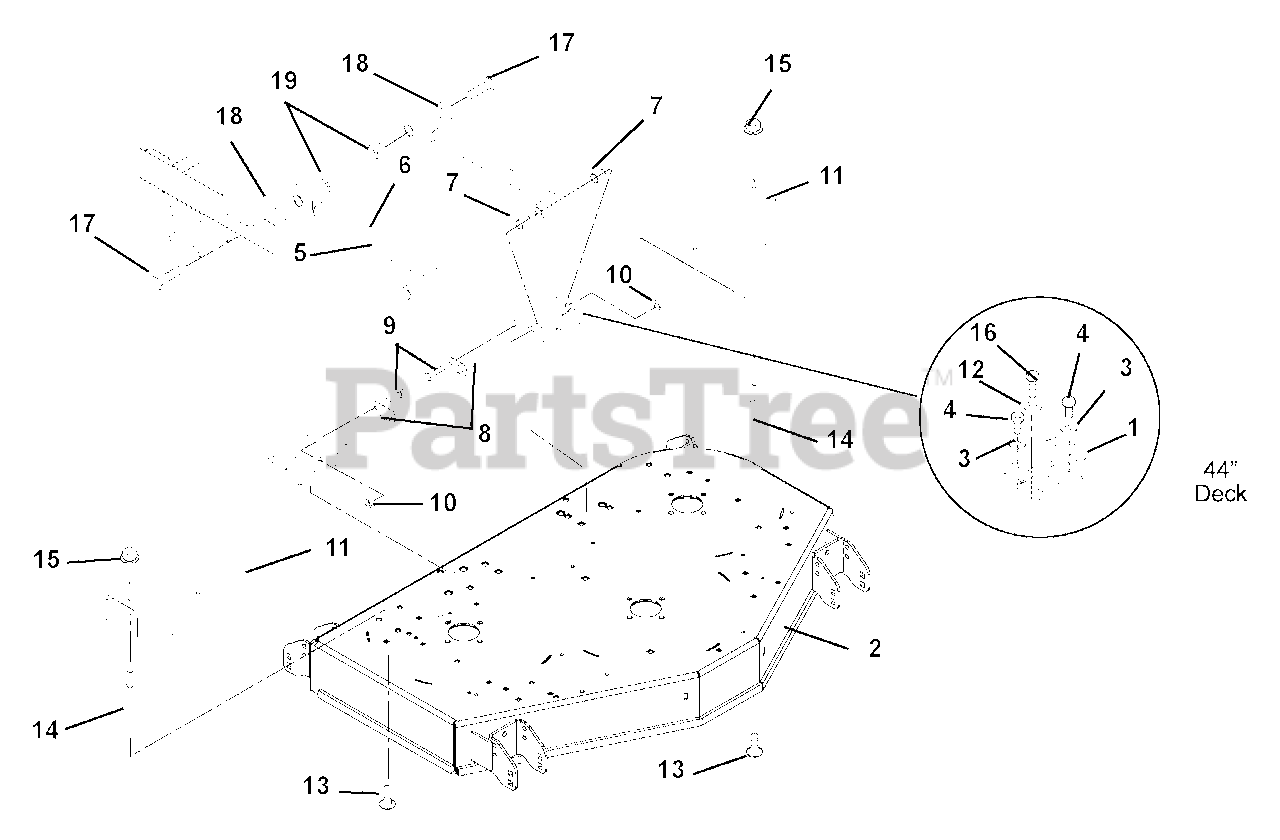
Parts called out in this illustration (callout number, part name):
1	BRACKET, MOWER MOUNT (REAR)
2	WMT, 44 REAR DISCHARGE
3	@WSHR-LK .50X.125 REG YWZC
4	@BLT-HEX .50-13X1.00 GR5 YWZC
5	ASSY, MOWER MOUNTING
6	MOWER MTG ARM - BLACK
7	BRG, .750 X .875 X 1.000
8	WELDMENT, MOWER MTG. PIN
9	@BLT-HEX .38-16X.75 GR5 YWZC
10	@NUT-LK-TOP-FLG .38-16 YWZC
11	GUARD, PULLEY-44,48 (RED)
12	@WSHR-LK .38X.094 REG YWZC
13	BLT,RDHDSQNK .31-18X.75 LOCTIT
14	STANDOFF, 2.75 X 5/16-18
15	@NUT-LK-TOP-FLG .31-18 YWZC
16	@BLT-HEX .38-16X1.00 GR5 YWZC
17	BLT-HEX .875-9X2.75 GR5 YWZC
18	WSHR-FL-STL .890X1.500X.1196YZ
19	NUT-LK-CTR .875-9 YWZC
